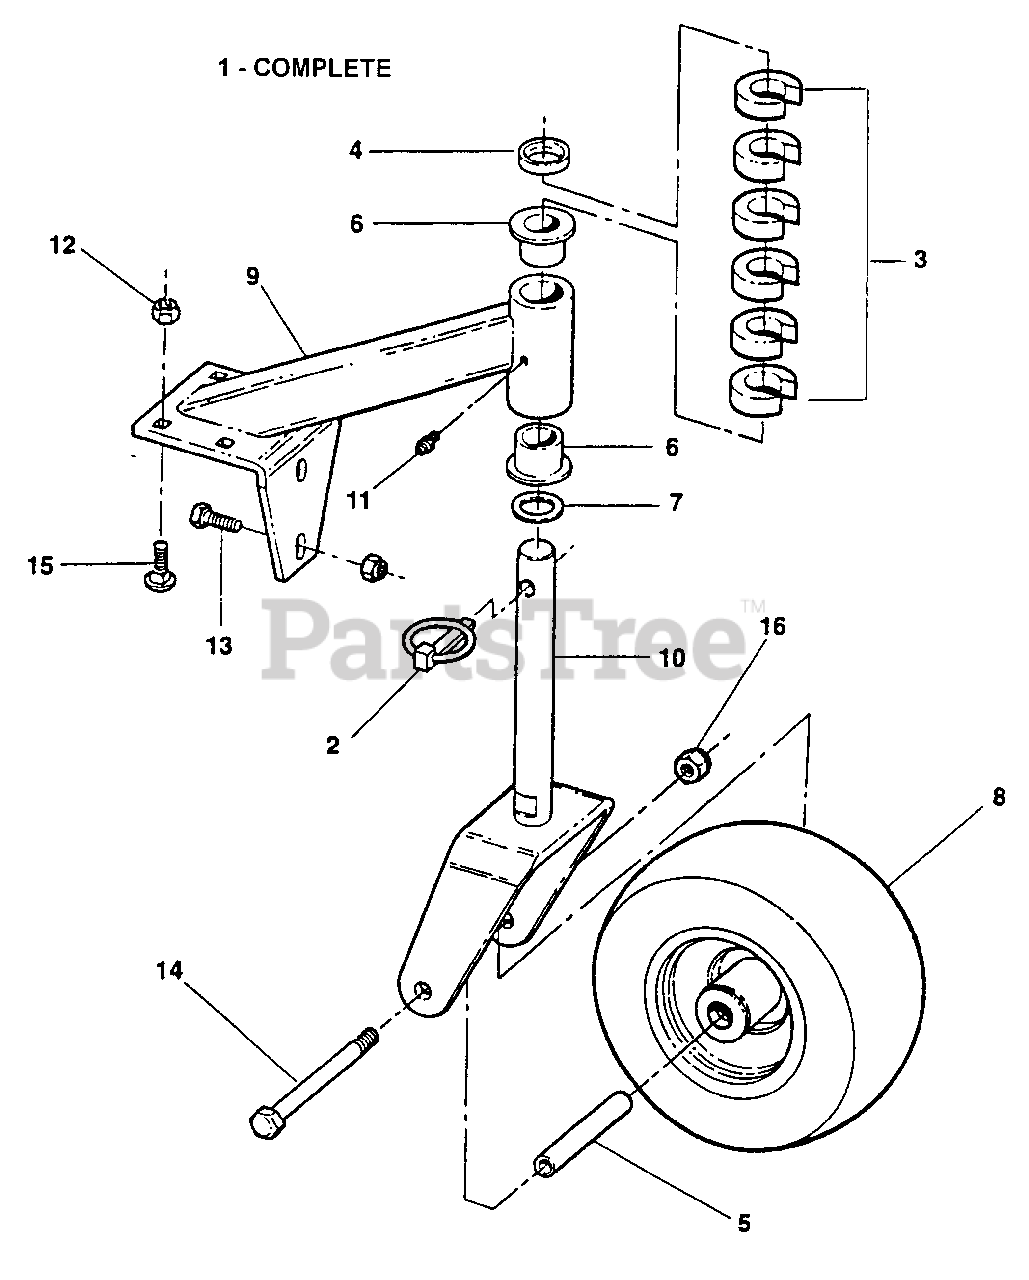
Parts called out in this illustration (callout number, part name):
1	ASSEMBLY, Rear Caster, 73" OFZ Deck
2	PIN, 7/16" Lynch (HD)
3	SPACER, Caster
4	SPACER, 1" x 1 3/8 x .30" (PM)
5	SPACER, Axle Sleeve
6	BUSHING, Caster
7	BUSHING, 1" Machine
8	ASSEMBLY, Wheel/Tire, 9 x 3.50 - 4
9	SUPPORT, Caster (Weldment)
10	YOKE, Caster (Weldment)
11	FITTING, Lube, 1/4-28 Straight
12	NUT, 3/8-16 HEX NYLON LOCK
13	BOLT, 3/8-16 X 1" GD5 CZ
14	BOLT, 1/2-13 X 5-1/2" GD5 YZ
15	BOLT, 3/8-16 x 1" Carriage
16	NUT, 1/2-13 HEX NYLON LOCK
